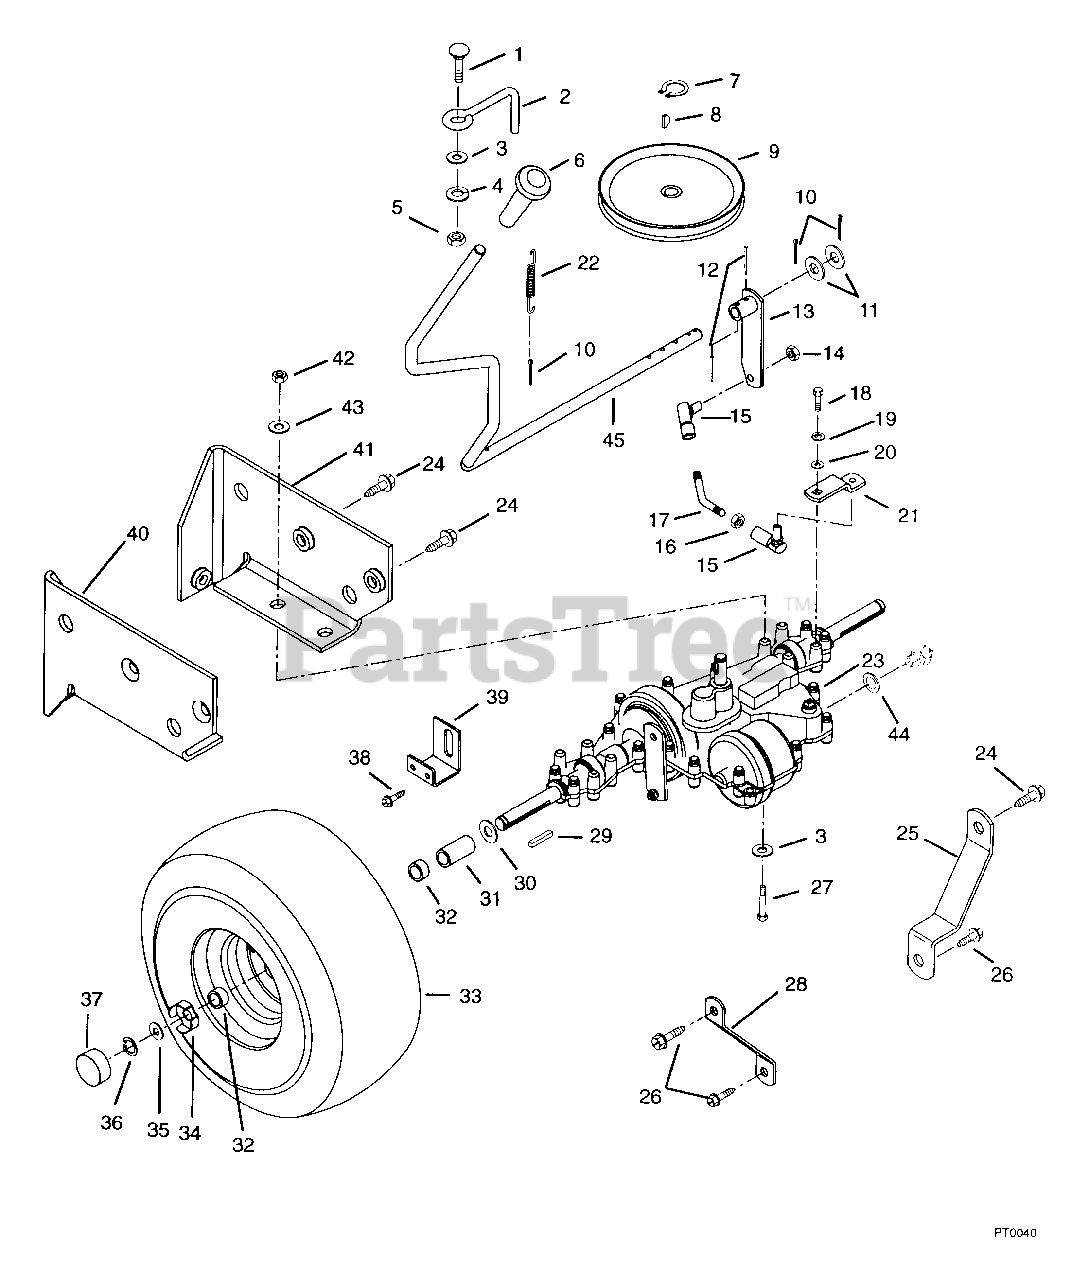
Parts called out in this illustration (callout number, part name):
1	BLT-RDHDSQNK.31-18X.75GR5SHTPL
2	FINGER - BELT
3	WSHR-FL-STL.344X.688X.065PL
4	WSHR-LK .312X.097 PL HVY
5	NUT-HEX .312-18
7	RG-RTNG-EXT .625X.035
8	KEY-WDRF .188X.75X.313 SAE 9
9	PLY-TRANS 7.00X.626
10	PIN-COTR .12X1.0 PL
11	WSHR-FL-STL .520X.827X.062 YZ
12	PIN-GRV .188X1.25 TP A
13	ARM & HUB
14	NUT-LK-CTR .312-24 PL
15	BALL JOINT- SNAP IN
16	NUT-JAM .312-24 PL
17	LINK - SHIFT
18	BLT-HEX .25-28X.75 PL GR8
19	WSHR-LK .250X.077 HVY PL
20	WSHR-FL-STL .328X1.0X.094 PL
21	ARM - SHIFT 6 SPD
22	SG-TENS .063X.44X1.56
23	TRANSAXLE - GEAR 6 SPEED MST
24	SCR-TAP .375-16X.75 HWH PL TR
25	STRAP - TORQUE,LH 6 SPD
26	SCR-TAP .312-18X.75 HWH PL TR
27	BLT-HEX .31-18X2.50 PL GR5
28	TORQUE STRAP
29	KEY-SQ .188X2.0X.188 SAE 8630
30	WSHR-FL-STL .755X1.375X.062 PL
31	BSHG-SLV .750X1.125X1.062
32	SPACER .760X1.000X.575
33	T/WHL ASSY 20X8.00-8
34	SPINDLE CUP
35	WSHR-FL-STL .755X1.375X.062 PL
36	RG-RTNG-EXT .750X.050
37	HUB CAP
38	SCR-TAP .312-18X.50 HWH TR BL
39	SHIFT GUIDE BRACKET
40	MOUNT - TRANS. RH
41	MOUNT - TRANS. LH
42	NUT-LK-TOP .312-18 GR C PL
43	WSHR-FL-STL .328X.875X.062 PL
44	O-RING .500X.629X.070
45	LEVER - SHIFT
